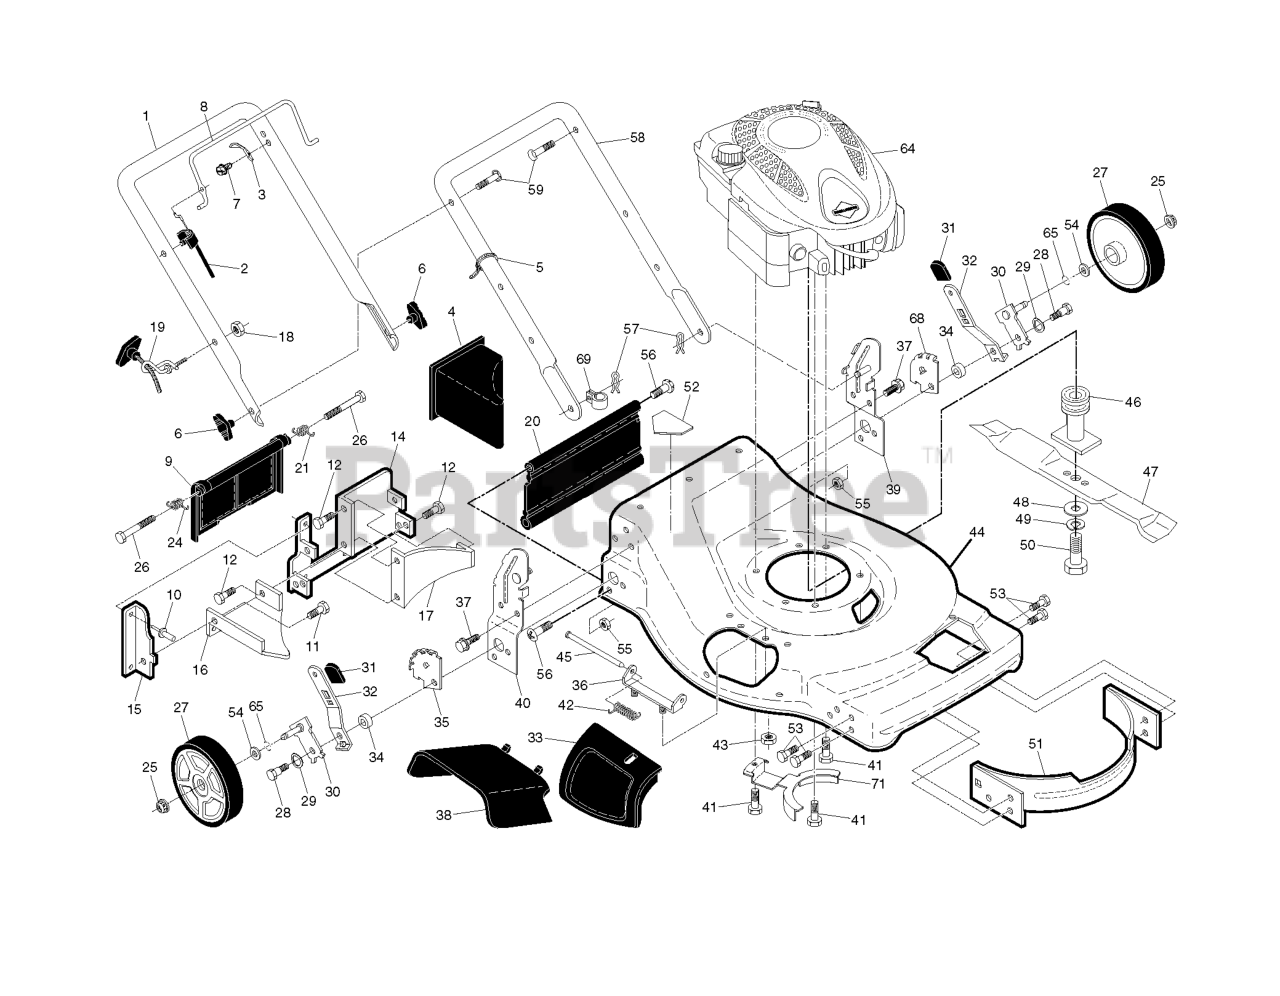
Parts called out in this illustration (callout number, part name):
2	CABLE.ENGINE BRAKE.MZR
3	BRACKET UPSTOP
4	PLUG.MULCH.22RD
5	TIE GUIDE
6	KNOB.WING.PLASTIC.BLACK
8	BAIL.MZR.CREA.ORANGE
9	REAR DOOR ASSY
10	RIVET BLIND
11	SCREW.HXTAP.10-24
12	SCREW 14-20 X 5/8
14	PLATE.BACK
15	SIDE BAFFLE
16	DISCHARGE BAFFLE
17	REAR BAFFLE
18	NUT
19	RB GUIDE.ROPE.STD.BLK.ZIN WSL
20	SKIRT.REAR.22RD/SD.FO/VE
21	SPRING.LH.22.REAR.DOOR.EZ.EMPT
24	SPRING.RH.22.REAR.DOOR.EZ.
25	NUT.HEX.FLANGE.3/8-16.LO(3 2)
27	WHEEL & TIRES ASSY, FRONT
28	BOLT SHOULDER 3/8 -16X1
29	WASHER.CURVED.CYLINDRICAL
30	AXLE ARM ASSY.
31	SELECTOR KNOB
32	SELECTOR SPRING, FRONT
33	DOOR.MULCH.22.REAR.FWGD.GREY
34	SPACER.HEIGHT.ADJUSTER
35	WHEEL ADJUSTING BRACKET
36	BRACKET.ASM.HINGE.21.FWGD.
37	BOLT.HEX.HD.WASHER.5/16-18X.75
38	DEFLECTOR.CLIPPING.22.FGD
39	BRACKET.ASM.HDL.LT.EZEM.22.ORA
40	BRACKET.ASM.HDL.RT.EZEM.22.ORN
41	BOLT 3/8-16X1-1/8
42	SPRING.TORSION
43	LOCKNUT.NYLOC.1/4-20
44	HOUSING.22.TORUS.FWD.ORANGE.WA
45	ROD.HINGE.21
46	ADAPTER.BLADE/PULLEY.25M
47	BLADE.22.MULCH.STANDARD
48	WASHER,HARDEN
49	LOCKWASHER
50	SCREW, HEX HD 3/8-24 X 1-3/8
51	FRONT BAFFLE KIT
52	DANGER DECAL
53	SCREW 1/4X20
54	WASHER.FLAT.1/2
55	LOCKNUT
56	HINGE SCREW
57	HAIRPIN COTTER
58	HANDLE.LOWER.D-STRAIT.GREY
59	BOLT, HANDLE 5/16-18X1.75
65	O-RING..070X.487.NEOPRENE
68	WHEEL ADJUSTING BRACKET LH
69	CLIP.CABLE.BLK
71	BRACKET.ENG/BELTKEEPER.BZP
